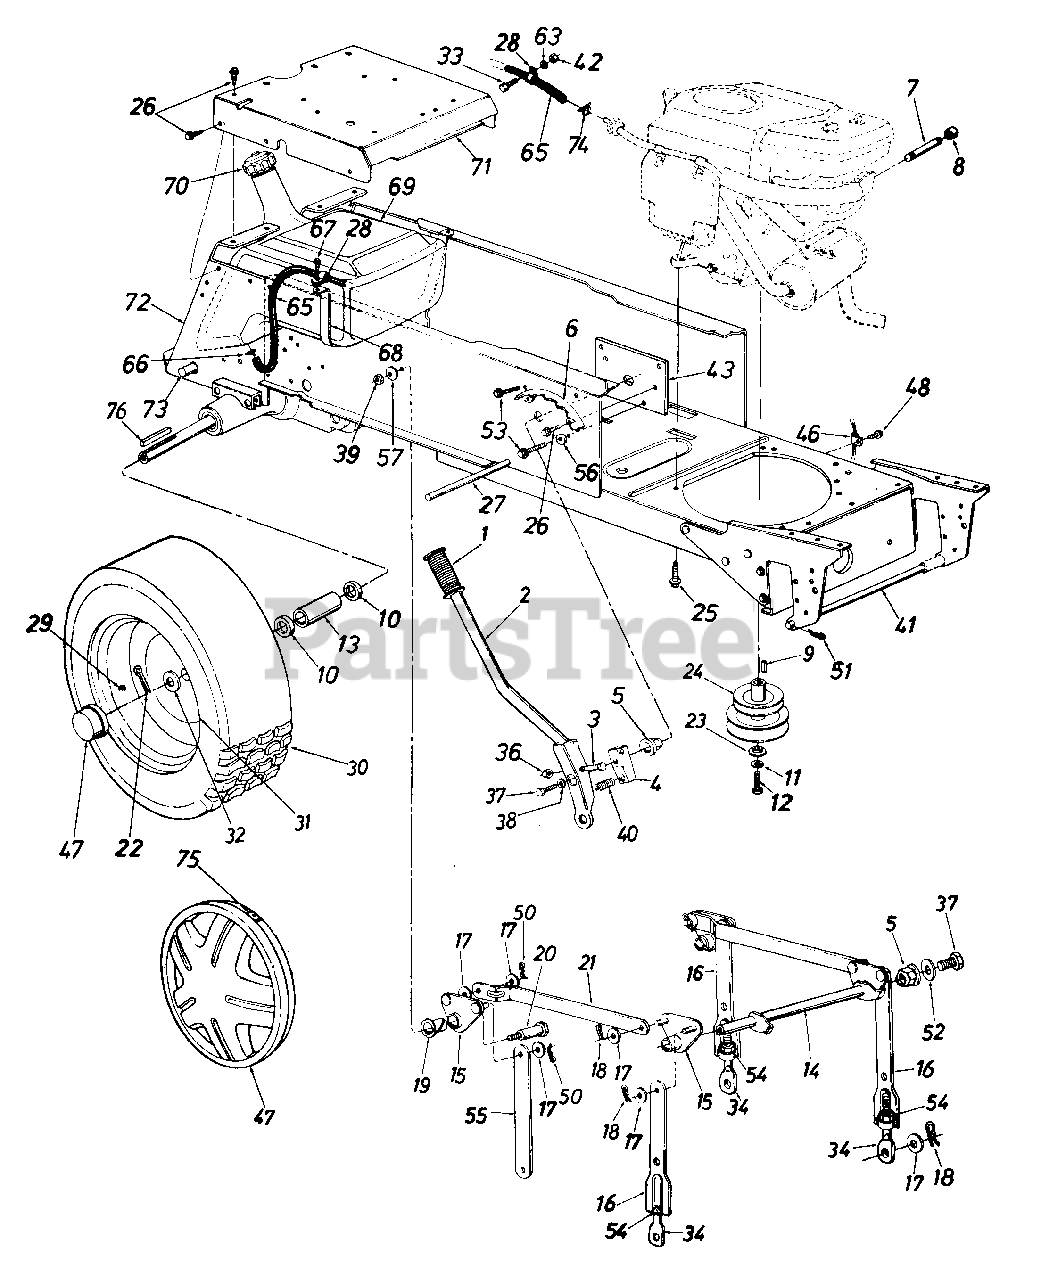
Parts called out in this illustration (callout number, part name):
1	Grip
2	Lift Handle Ass'y.
3	Hex Bolt 5/16-18 x 1.5" Lg.
4	Lift Shaft Drive
5	Plastic Hex Brg. 5/8" I.D.
8	Pipe Cap 3/8-18 Npt.
9	Sq. Key 114" x 114" x 1.50" Lg.
10	Fl-Wash. 1.03" I.D. x 1.62" O.D.
11	L-Wash. 7/16" I.D.
12	Hex Scr. 7/16-20 x 1.50" Lg.
13	Spacer 1.0" I.D. x 1.25" O.D.
14	Lift Shaft Ass'y.
15	Lift Pivot Brkt. Ass'y.
17	Fl-Wash. 112" I.D. x 1.00" O.D. x .090"
18	Hairpin Cotter
19	Nyliner 518" I.D. x .88" Lg.
20	Shld. Bolt 5/8n Dia. x .96" Lg. 3/8-16
23	Flat Wash. .44" I.D. x 1.25" O.D. x .17"
24	Two-Step Engine Pulley
25	Hex Wash. Hd. Scr. 3/8-16 x 1.25" Lg.
26	Hex Thd. Rolling Scr. 5/16-18 x.75" Lg.
27	Running Board Rod
28	Clamp
29	Air Valve
33	Hex Bolt 1/4-20 x .62" Lg.
34	Eye Bolt Adj. Link 1/2-13 Thd.
36	Hex Cent. L-Nut 5/16-18 Thd.
37	Hex Scr. 5/16-24 x .62" Lg.
38	L-Wash. 5/16" I.D.
39	Hex Top L-Nut 3/8-16 Thd.
40	Compression Spring
41	Deck Connecting Rod
42	Hex Nut 1/4-20 Thd.
47	Hub Cap
48	Hex Wash. Hd. TT-Tap Scr. 1/4-20 x .5" Lg.
50	Cotter Pin .09 Dia. x 1.0" Lg.
51	Int. Cotter Pin
52	Flat Wash. .34" I.D. x 1.12" O.D. x .125"
53	Hex Wash. Hd. AB-Tap Scr. 5/16-24 x .5" Lg.
54	Hex Nut 1/2-13 Thd.
56	Fl-Wash. .344" I.D.
57	Bell-Wash. .4" I.D. x 1.13" O.D.
63	L-Wash. 1/4" I.D.
65	Fuel Line 50" Lg.
66	Hose Clamp
67	Hex AB-Tap Scr. 1/4 x .62" Lg.
68	Fuel Tank Strap
69	Gas Tank
70	Gas Gauge
71	Seat Plate
74	Hose Clamp
75	Spring Clip
76	Sq. Key 1/4" x 3" Lg.
